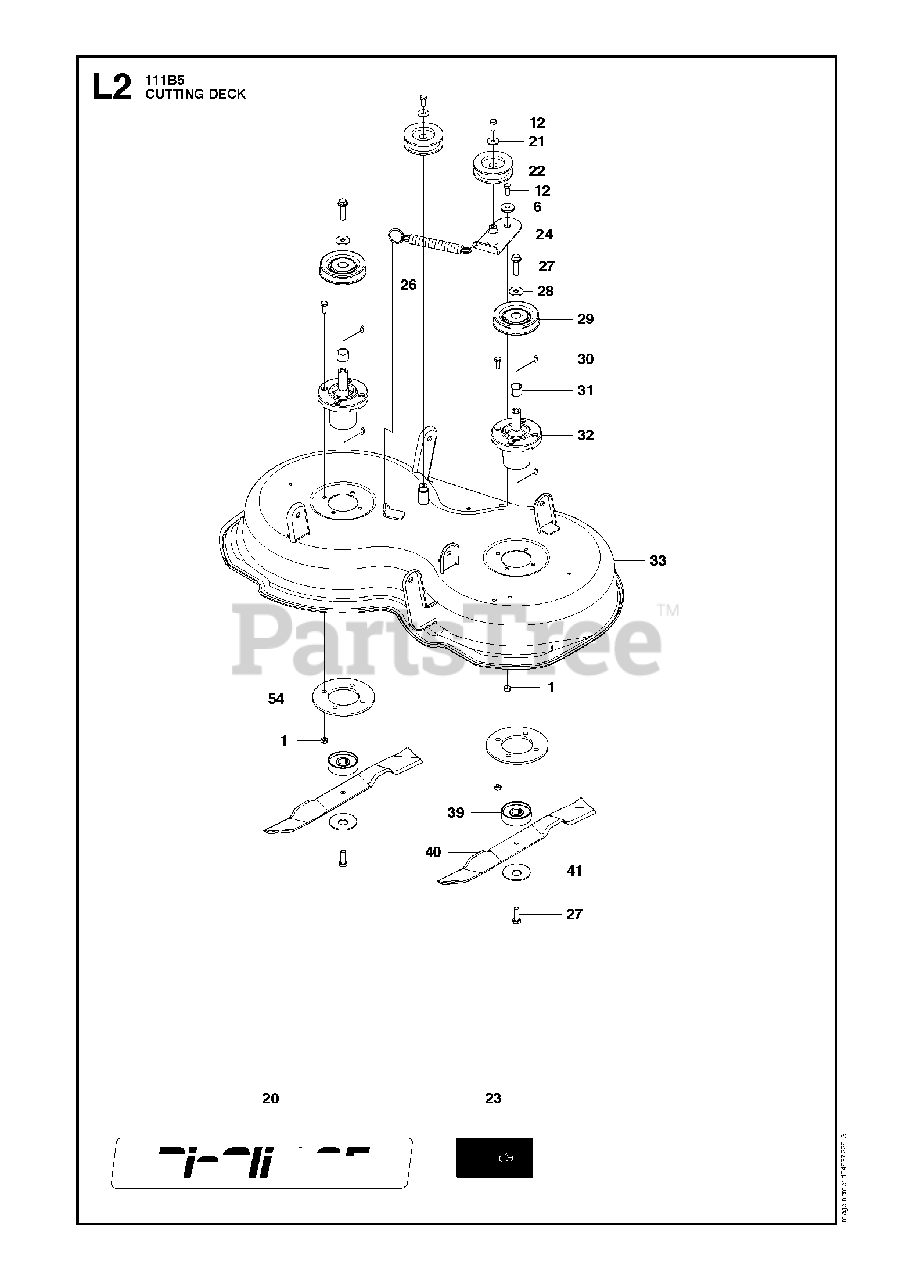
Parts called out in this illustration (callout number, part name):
1	METERING DIAPHRAGM
2	GASKET-METER DIAP
4	MIXTURE NEEDLE (132HBV)
5	SPRING/COMPRESSION
8	PUMP DIAPHRAGM
9	GASKET-FUEL PUMP
10	SCREW-IDLE SPEED
12	PIN
13	LEVER
15	INLET NEEDLEVALVE
16	SCREEN-DUTCH TWILL INLE
17	REPAIR PARTS KIT
18	INQUGASKET DIAPHRAGM
